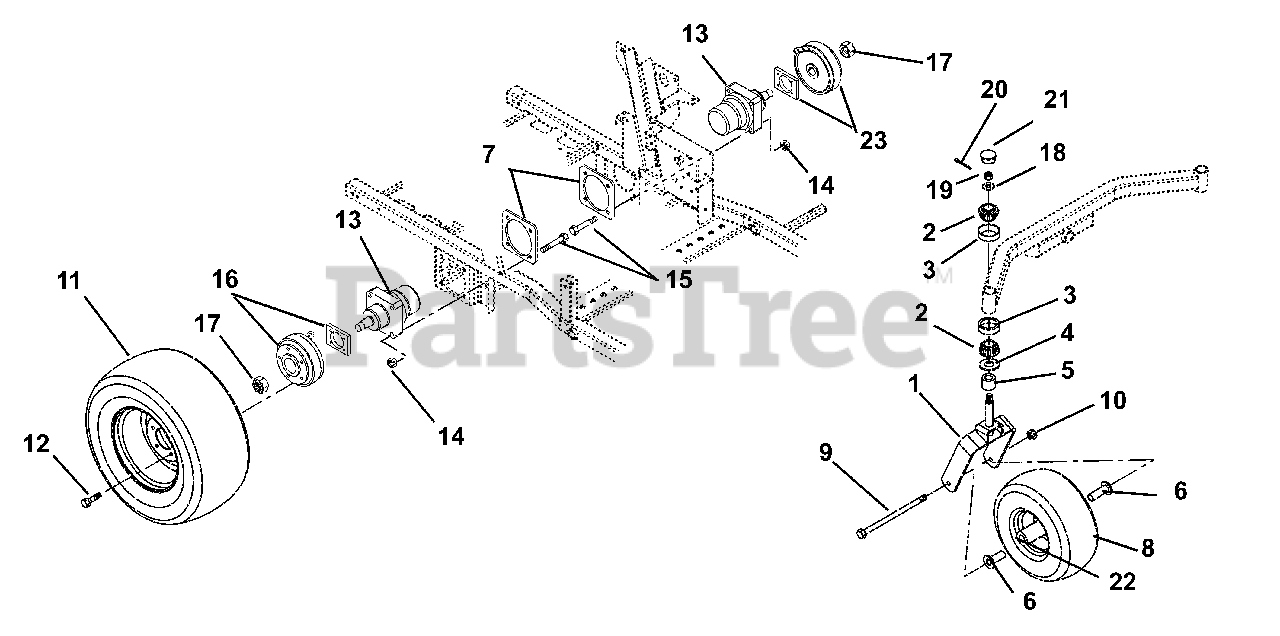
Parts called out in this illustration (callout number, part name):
1	Fork, Front
2	Bearing, Cone w/ Grease
3	Bearing, Cup 1.980 x .420
4	Bearing Seal 1.5 x 2 x .18
5	Spacer, PM, 1.03 I.D. x 1.5 O.D. x .375
6	Spacer, Wheel
7	Plate, Motor Support
8	Wheel/Tire Assembly
8	Tire, 15 x 6-6
9	Bolt, Hex .50-13 x 9.00 Grade 5
10	Nut, Locking Center .50-13
11	Tire/Wheel Assembly 24 x 12-12
11	Tire, Turfmaster 24 x 12-12
12	Bolt, Lug .50-20 x 1.38 Grade 8, 60 Degree
13	Hydraulic Wheel Motor
14	Nut, Locking Top Flange .50-13
15	Bolt, Wheel Motor .50-13 x 2.75
16	Brake, Right Hand Park
17	Nut , Lock Jam Patch
18	Washer, Flat Steel .755 x 1.375 x .062
19	Nut, Slotted .75-16
20	Pin, Cotter .16 x 1.00
21	Cap, Dust
22	Bearing, 25mm I.D. x 52mm OD x 15mm
23	Brake, Left Hand Park
